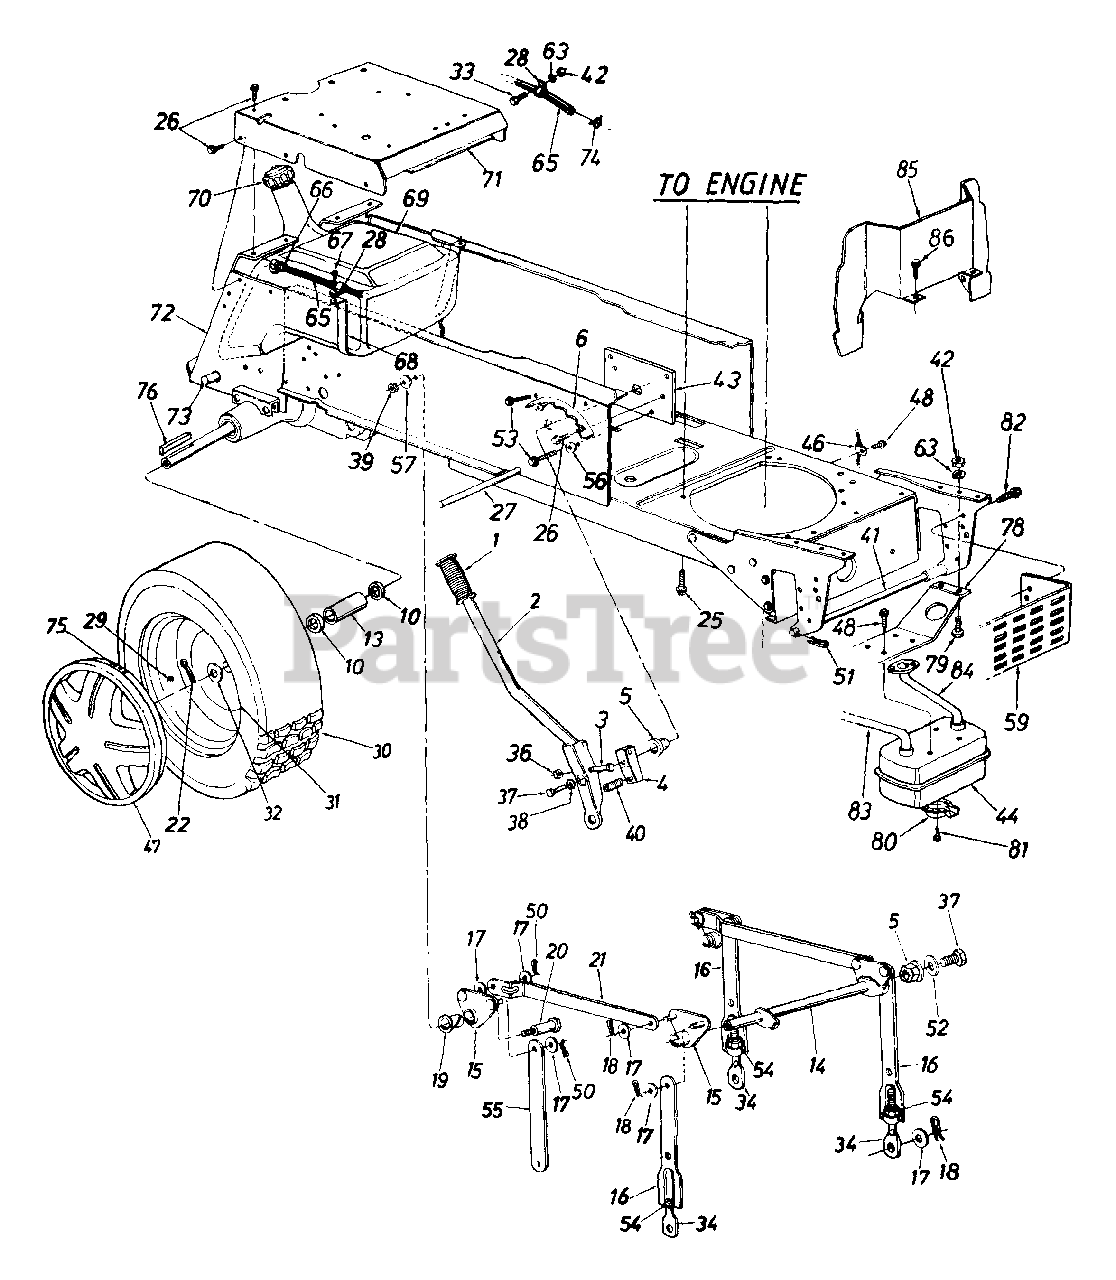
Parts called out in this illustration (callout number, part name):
1	Grip
2	Lift Handle Ass'y.
3	Hex Bolt 5/16-18 x 1.5" Lg.
4	Lift Shaft Drive
5	Plastic Hex Brg. 5/8" I.D.
10	Fl-Wash. 1.03" I.D. x 1.62" O.D.
13	Spacer 1.0" I.D. x 1.25" O.D.
14	Lift Shaft Ass'y.
15	Lift Pivot Brkt. Ass'y.
17	Fl-Wash. 1/2" I.D. x 1.00" O.D. x .090"
18	Hairpin Cotter
19	Nyliner 5/8" I.D. x .88" Lg.
20	Shld. Bolt 5/8" Dia. x .96" Lg. 3/8-16
25	Hex Wash. Hd. Scr. 3/8-16 x 1.25" Lg.
26	Hex Thd. Rolling Scr. 5/16-18 x .75" Lg.
27	Running Board Rod
29	Air Valve
33	Hex Bolt 1/4-20 x .62" Lg.
34	Eye Bolt Adj. Link 1/2-13 Thd.
36	Hex Cent. L-Nut 5/16-18 Thd.
37	Hex Scr. 5/16-24 x .62" Lg.
39	Hex Top L-Nut 3/8-16 Thd.
40	Compression Spring
41	Deck Connecting Rod
42	Hex Nut 1/4-20 Thd.
46	Mounting Clamp
47	Hubcap
48	Hex Wash. Hd. TT-Tap Scr. 1/4-20 x .5" Lg.
50	Cotter Pin .09 Dia. x 1.0" Lg.
51	Int. Cotter Pin
52	Flat Wash. .34" I.D. x 1.12" O.D. x .125"
53	Hex Wash. Hd. AB-Tap Scr. 5/16-24 x .5" Lg.
54	Hex Nut 1/2-13 Thd.
56	Fl-Wash. .344" I.D.
57	Bell-Wash. .4" I.D. x 1.13" O.D.
59	Heat Shield
63	L-Wash. 1/4" I.D.
65	Fuel Line 46" Lg.
67	Hex AB-Tap Scr. 1/4 x .62" Lg.
68	Fuel Tank Strap
75	Spring Clip
76	Sq. Key 1" x 3" Lg.
78	Muffler Mounting Brkt.
79	Hex Bolt 1/4-20 x .62" Lg.
80	Muffler Deflector
81	Hex Wash. Hd. F-Tap Scr. #8 x .32" Lg.
82	Hex Wash. Hd. TT-Tap Scr. 5/16-18 x .62" Lg.
83	Exhaust Tube - R.H.
84	Exhaust Tube - L.H.
